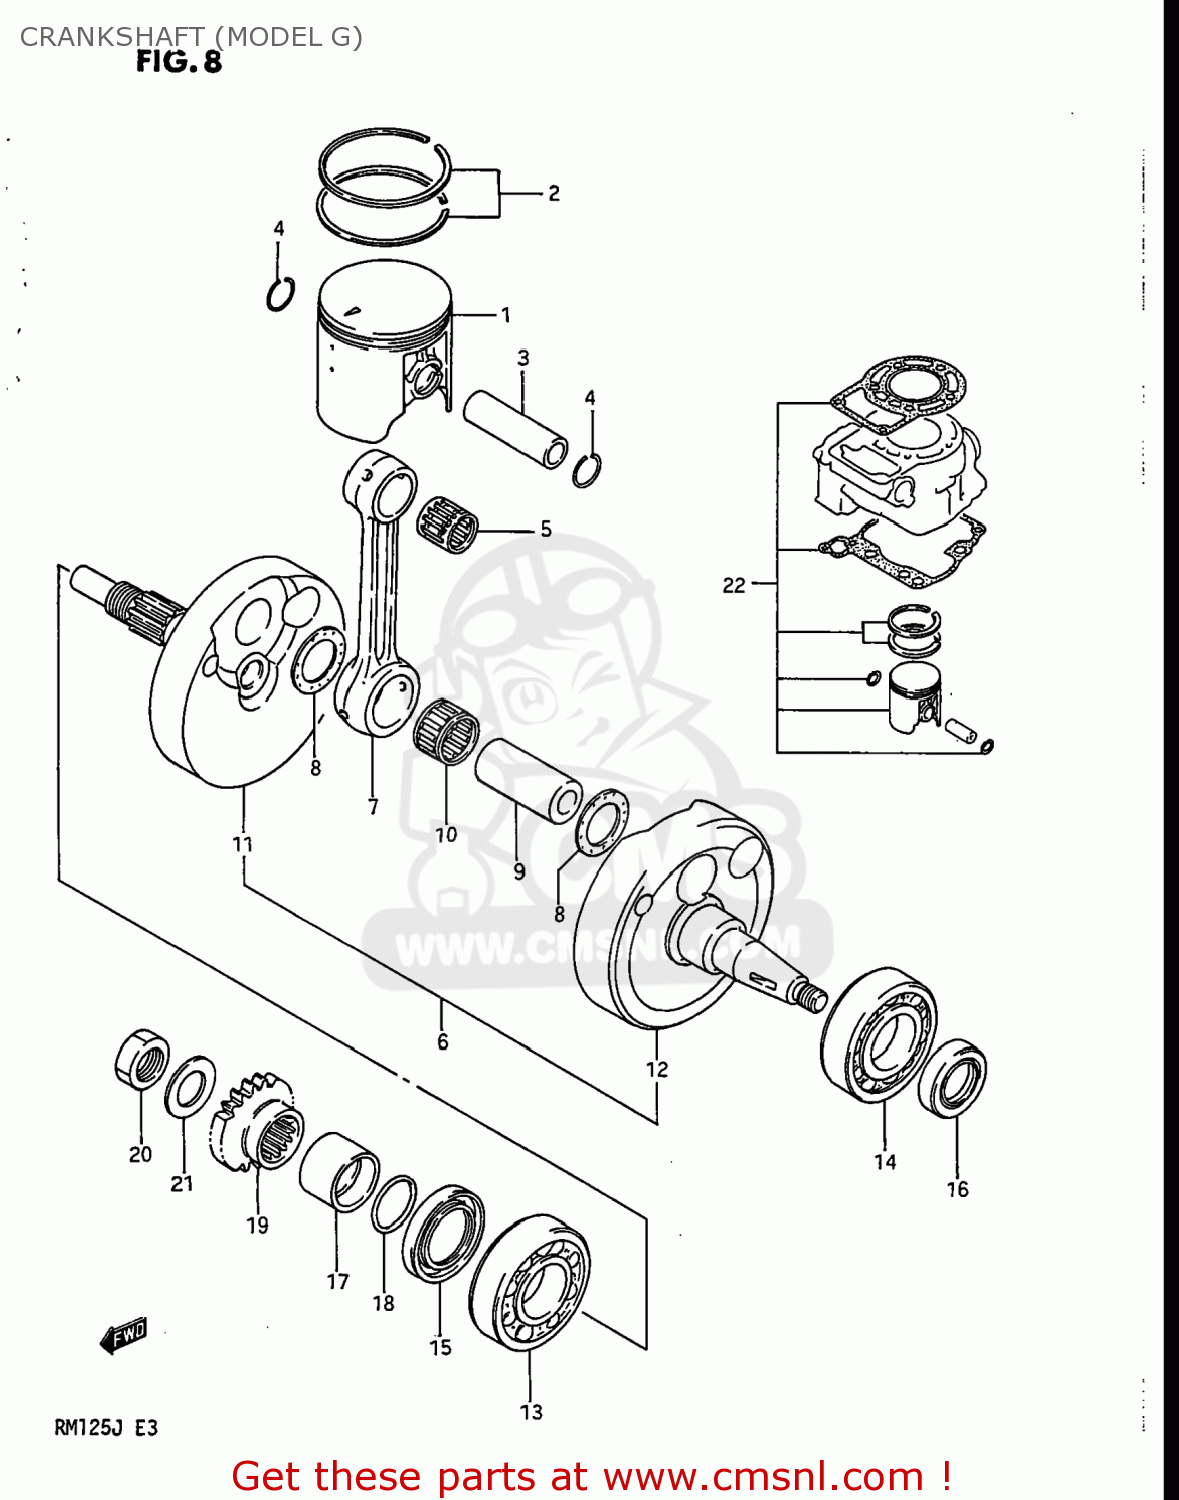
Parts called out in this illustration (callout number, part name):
1	PISTON
2	RING SET,PISTON
3	PIN,PISTON
4	RING,SNAP 14MM
5	BEARING
6	CRANKSHAFT ASSY
7	CONNECTING ROD
8	WASHER(22X35X1)
9	PIN,CRANK
10	BEARING
11	CRANKSHAFT,R
12	CRANKSHAFT,LEFT
13	BEARING
14	BEARING(25X52X15)
15	SEAL,OIL(28X40X8)
16	OIL SEAL
17	SPACER,PRIMARY DRIVE GEAR
18	O RING(D:2.4,ID:19.8)
19	GEAR,PRIMARY DRIVE
20	NUT
21	WASHER
22	PISTON KIT (STD)
